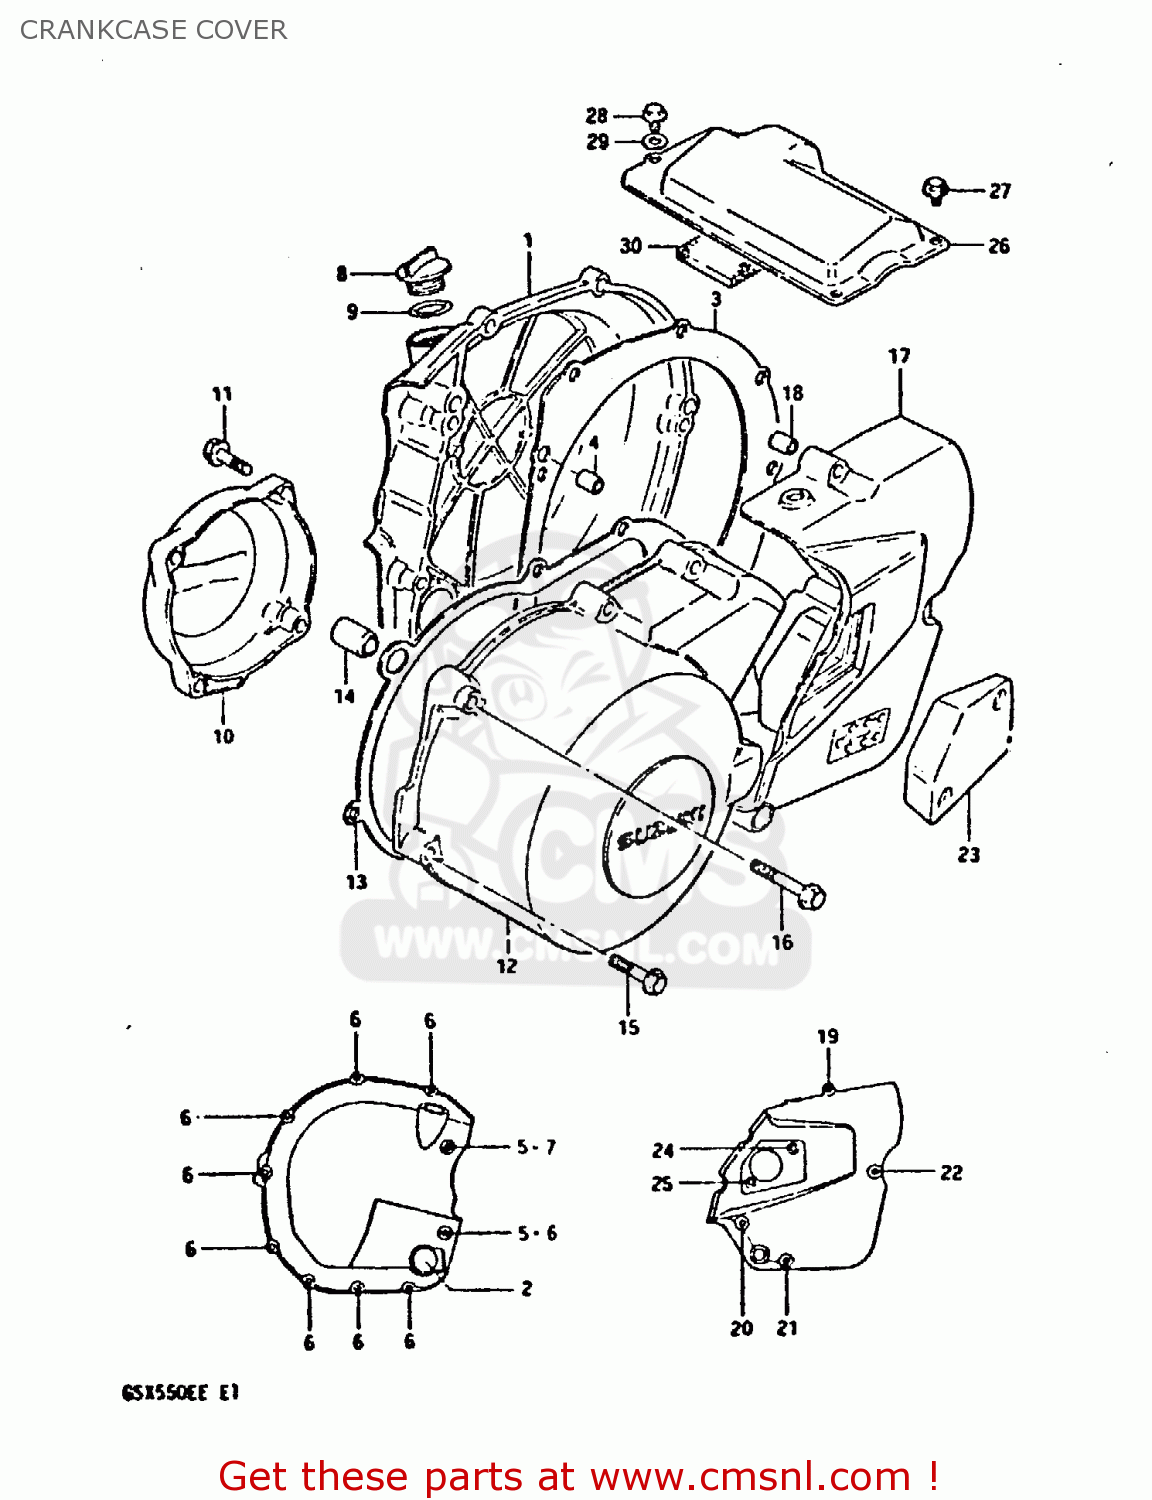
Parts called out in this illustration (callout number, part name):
1	COVER,CLUTCH
2	LENS,OIL LEVEL CHECK
3	GASKET,CLUTCH COVER (MCA)
4	PIN
5	WASHER
6	BOLT 6X25
7	BOLT 6X35
8	PLUG
9	O RING(D:3.1,ID:16.8)
10	COVER,CONTACT BREAKER
11	BOLT 6X25
12	COVER,MAGNETO
13	GASKET,MAGNETO COVER (MCA)
14	PIN (11X20)(SUS)
15	BOLT 6X30
16	BOLT
17	COVER,ENGINE SPROCKET
18	PIN
19	BOLT 6X40
20	BOLT (6X55)
21	BOLT 6X50
22	BOLT 6X80
23	CAP,CLUTCH RELEASE ADJUST
24	SCREW
25	SCREW
26	COVER,STARTER MOTOR
27	BOLT
28	BOLT
29	WASHER
30	DAMPER,STARTER MOTOR CLUTCH
